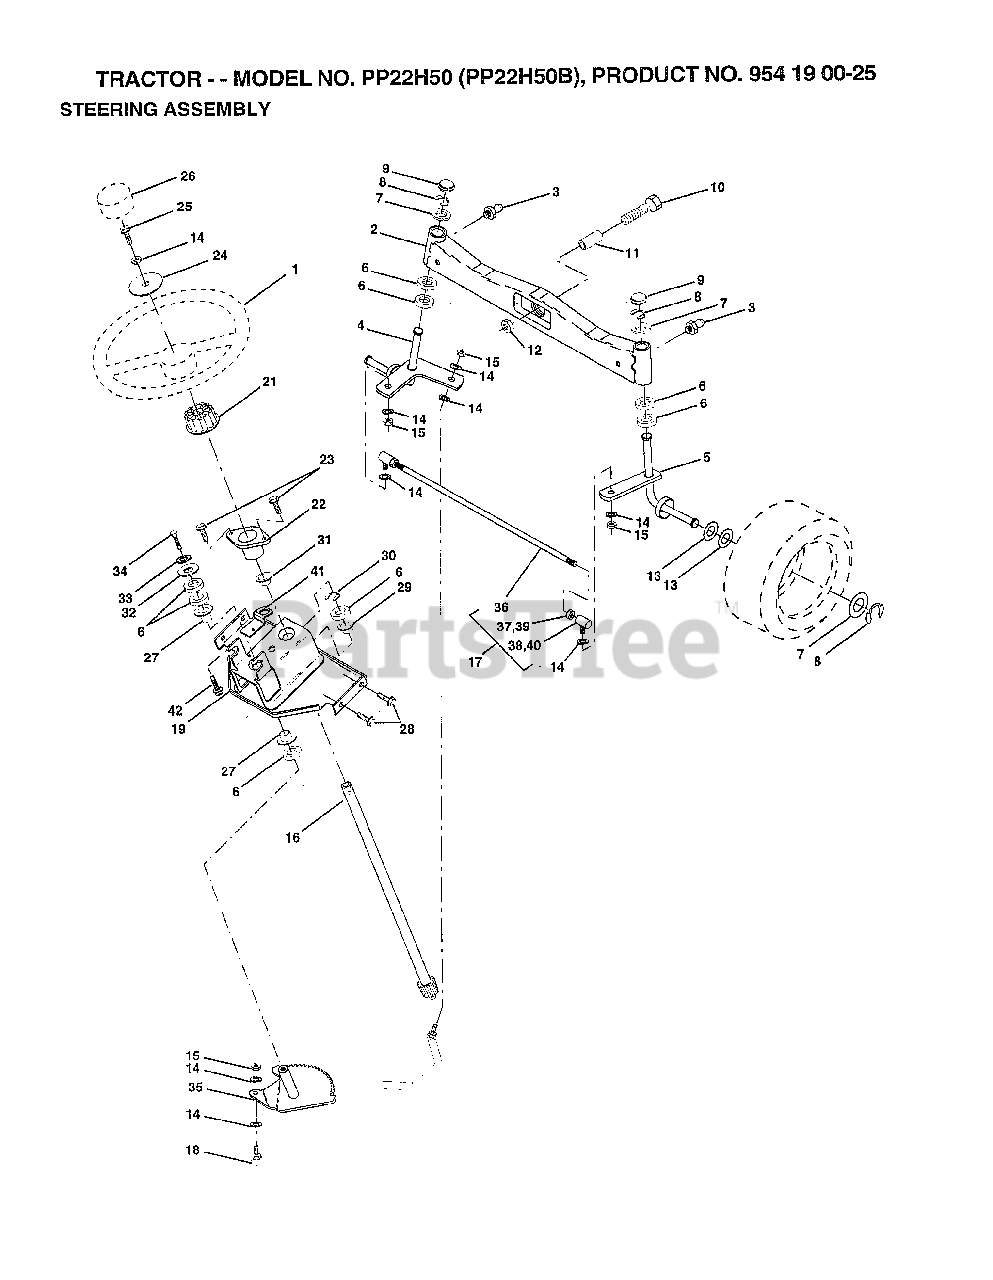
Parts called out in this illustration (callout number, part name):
3	ZERK M
4	SPINDLE ASM LH
5	SPINDLE ASM RH
6	WASHER .T
7	WASHER
8	RING
9	CAP
10	BOLT
11	SPACER BEARING
12	"NUT-LOC,FLANGE LT"
13	WASHER
14	LOCKWASHER
15	GRIPCO NUT
16	SHAFT.STEER.VGT
17	ROD.ASM.TIE.BALL
18	DRAGLINK.BALL.JOI
19	SUPPORT ASM-STEER
21	ADAPTER LT
22	"BUSHING,STEERING"
23	"SCREW-TT,10-32 FL"
24	WASHER T
25	BOLT
26	"INSERT,STR WHEEL"
27	COL. SRTG. BEAR.
28	SCREW
29	"FLANGE GT, BEAR."
30	KLIP RING
31	BUSHING.NYLINER.
32	WASHER
33	LOCKWASHER
34	BOLT
35	GEAR.ASM.SECTOR.
37	NUT
38	JOINT.RH
39	NUT
40	JOINT.LH
41	"BRKT-SW, INTER"
